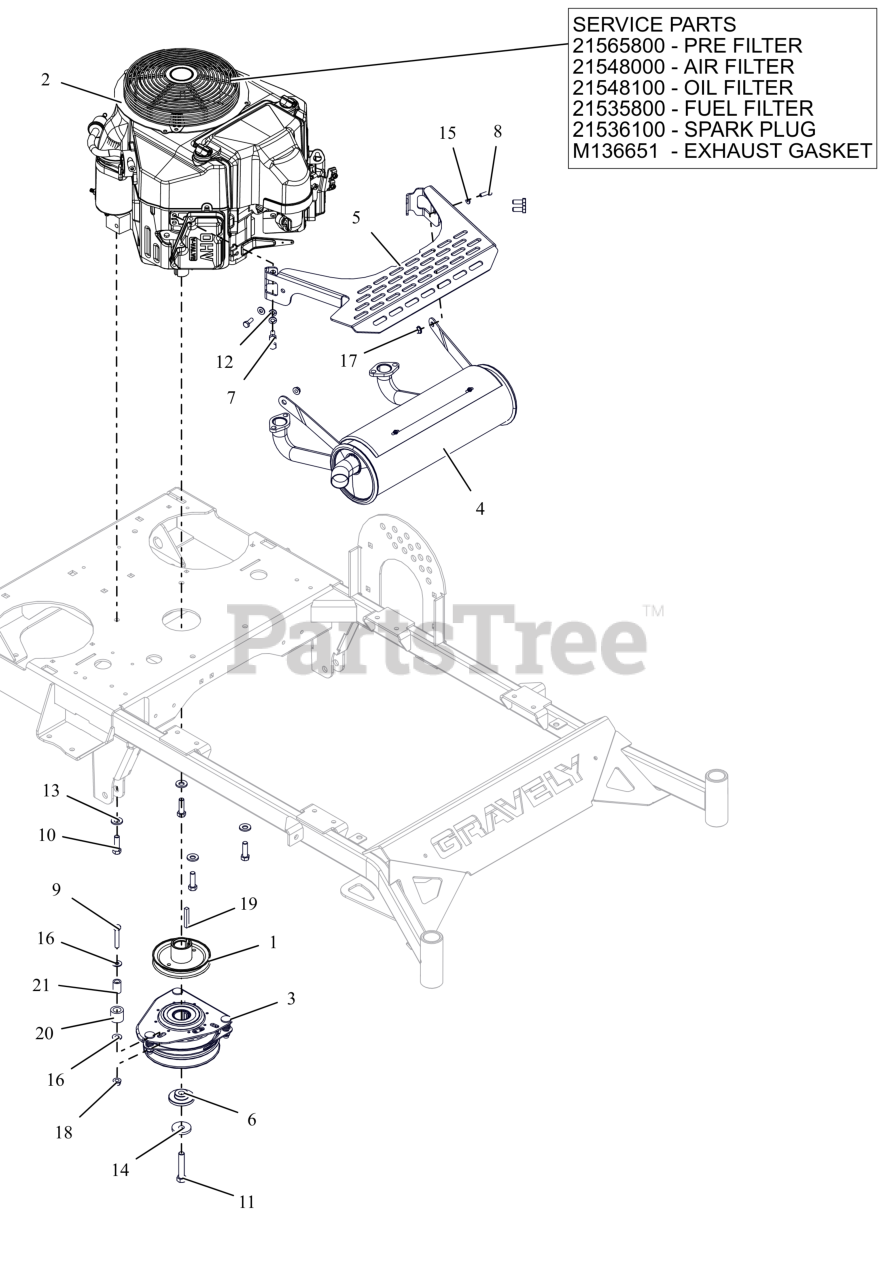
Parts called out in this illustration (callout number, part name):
1	SHEAVE, ENGINE 4.50 x 1.004 ID (BLACK)
2	ENG. KAW FS600
2	PRE FILTER, KAWASAKI FS
2	AIR FILTER, KAWASAKI FR
2	OIL FILTER, KAWASAKI FR
2	FILTER,OIL - KAW
2	PLUG, SPARK
2	GASKET, MUFFLER #
3	CLUTCH, OGURA GT1A-AR03
4	MUFFLER, KAW FS PROWALK
5	SHIELD, MUFFLER
6	BSHG-FLG .469X1.06X.574X2.0
7	BLT, HEX M8-1.25X20 G8.8 ZCC
8	BLT, HEX .25-20X.75 G5 ZCC
9	BLT, HEX .31-18X1.75 G5 ZCC
10	BLT, HEX .38-16X1.25 G5 ZCC NT
11	BLT, HEX 0.4375-20X2.25 G8 ZCC NT
12	WSHR,LK-REG .312X.078 ZCC
13	WASHER, 3/8" SPRING DISC
14	WASHER, 7/16" SPRING DISK
15	WSHR,FLT .281X.625X.065 ZCC
16	WSHR, FLT .312X.734X.065 ZCC
17	NUT-LK-CTR-FLG .25-20 ZC120
18	NUT,LK-CTR-FLG .31-18 GF ZCC
19	KEY-STR .25X1.75X.25
20	BUMPER,RUBBER .62X1.0X.88 LG
21	BUSH.,S.391X.622X.950 ST
